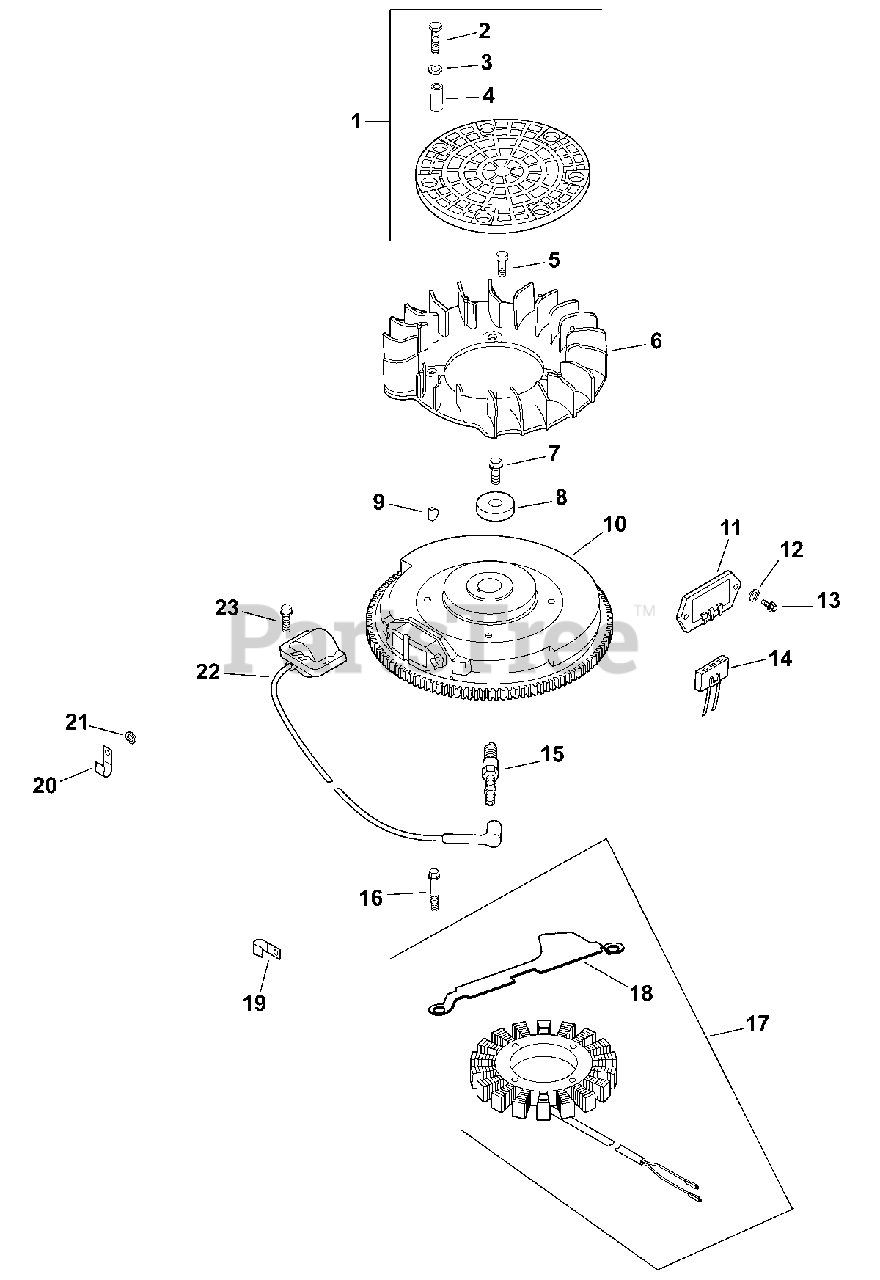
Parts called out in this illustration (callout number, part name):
1	KIT, GRASS SCREEN
2	SCREW, SLT HD CAP M4X0.7X25
3	WASHER, FLAT 3/16"
4	SPACER - DISCONTINUED
5	BOLT, SHOULDER
6	FAN (DOMED)-USE 24 157 17-S
7	SCREW, FLG M10X1.5X45 - (#25086361S)
8	WASHER, FLAT 13/32"
9	KEY, 3/16" X 5/8"
10	FLYWHEEL, PAINTED-USE 24 025 55-S
11	REG/RECT-15 AMP (KM)-USE 41 403 10-S
12	WASHER, FLAT 3/16"
13	SCREW, PHL HD #11-16X7/8"
14	CONNECTOR, BODY (KM)-USE 25 155 41-S
15	PLUG, SPARK (STD)
16	SCREW, M5X0.8X25 - (#25086402S)
17	STATOR KIT - USE 237878-S
18	BRACKET, STATOR WIRE-USE 24 126 139-S
19	CLIP, CABLE
21	WASHER, FLAT 1/4" (O.D. 1/2")
22	MODULE, IGNITION-USE 24 584 45-S
23	SCREW, FLG THD FRM M5X.8X20-(#25086399S)
